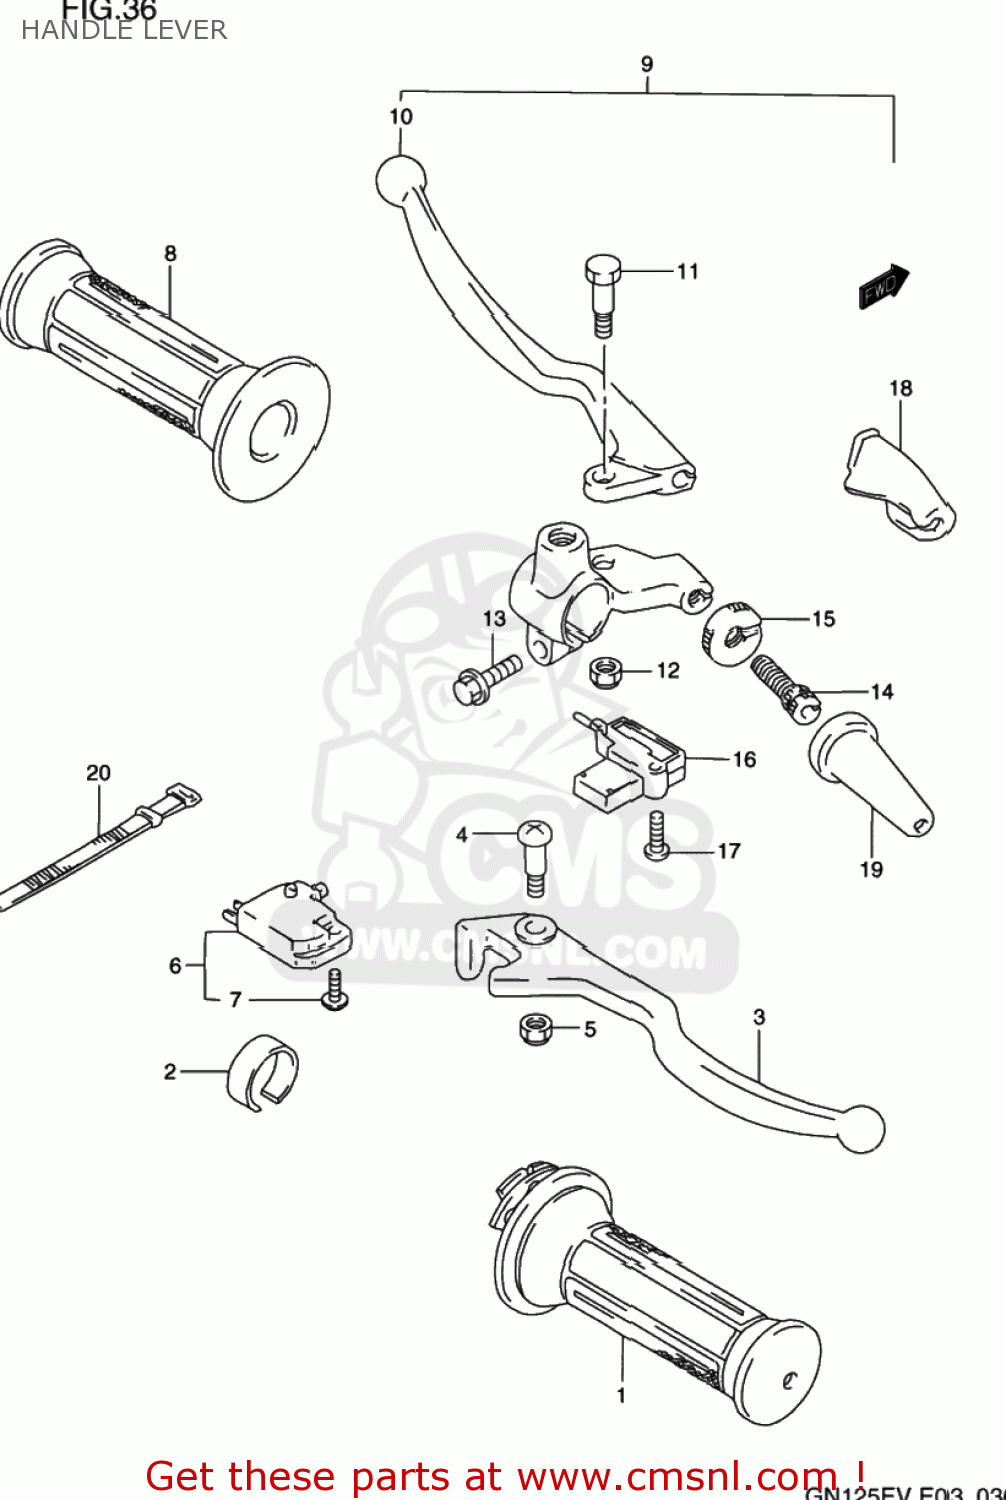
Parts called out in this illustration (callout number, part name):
1	GRIP,THROTTLE
2	SPACER,HANDLE SWITCH,R
3	LEVER,BRAKE
4	SCREW,BRAKE LEVER
5	NUT
6	SWITCH ASSEMBLY,STOP
7	SCREW
8	GRIP,L
9	LEVER ASSY,CLUTCH
10	LEVER,CLUTCH
11	BOLT,LEVER SET
12	NUT
13	SCREW
14	ADJUSTER,WIRE
15	NUT,LOCK
16	SWITCH,CLUTCH
17	SCREW
18	COVER,CLUTCH LEVER
19	BOOT,CLUTCH CABLE
20	CLAMP(L:120)
